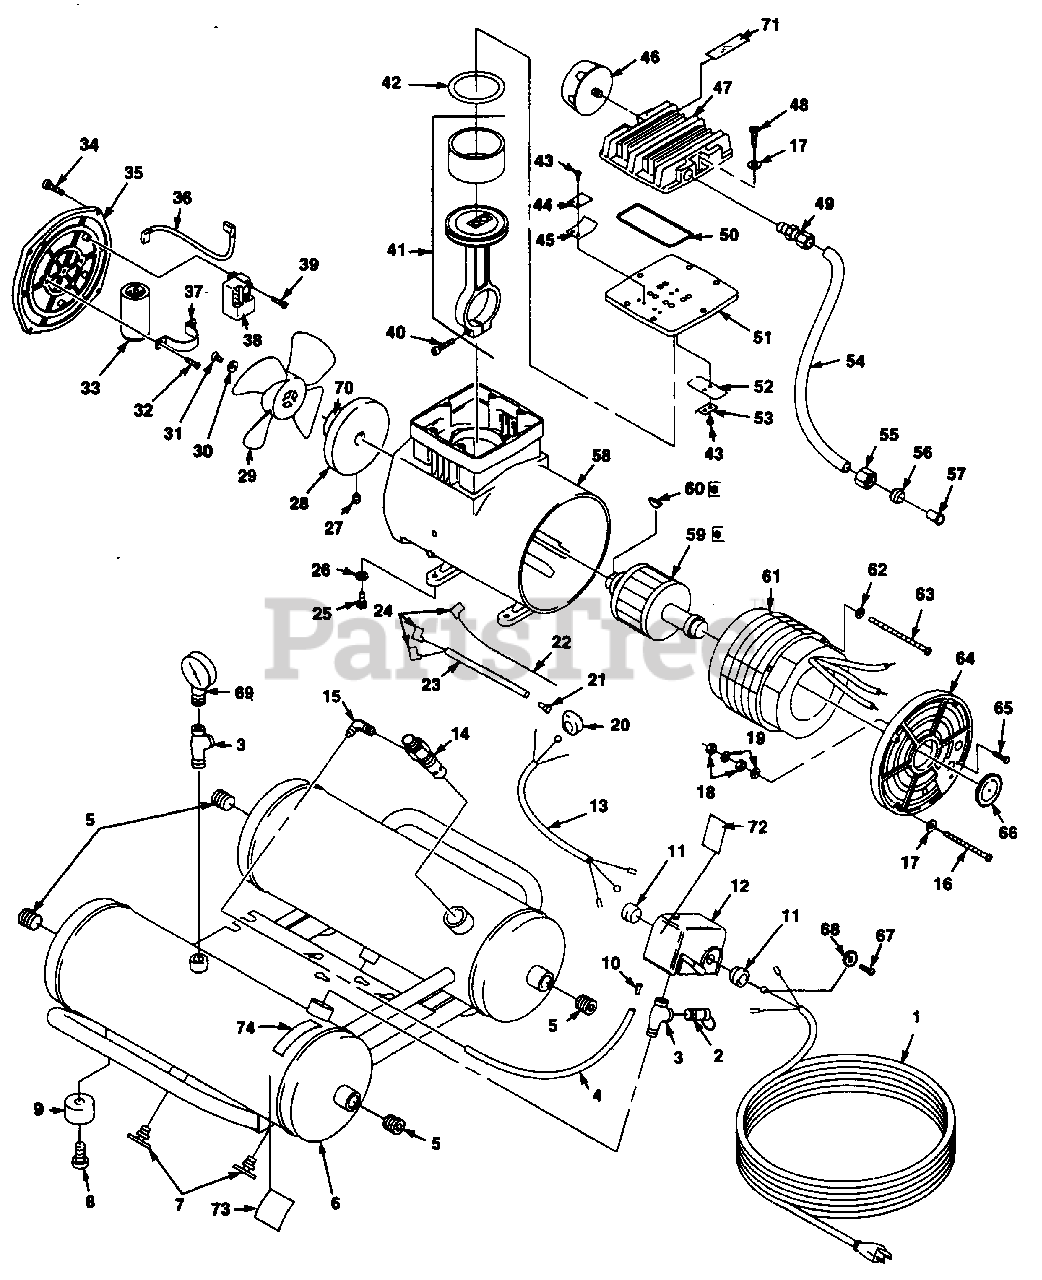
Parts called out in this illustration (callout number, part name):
8	SCREW TBO
25	SCREW-Mach Hex Hd.(1/4-20 X 1/2")
26	WASHER, LOCK
40	HEX SCREW
52	VALVE FLAPPER
